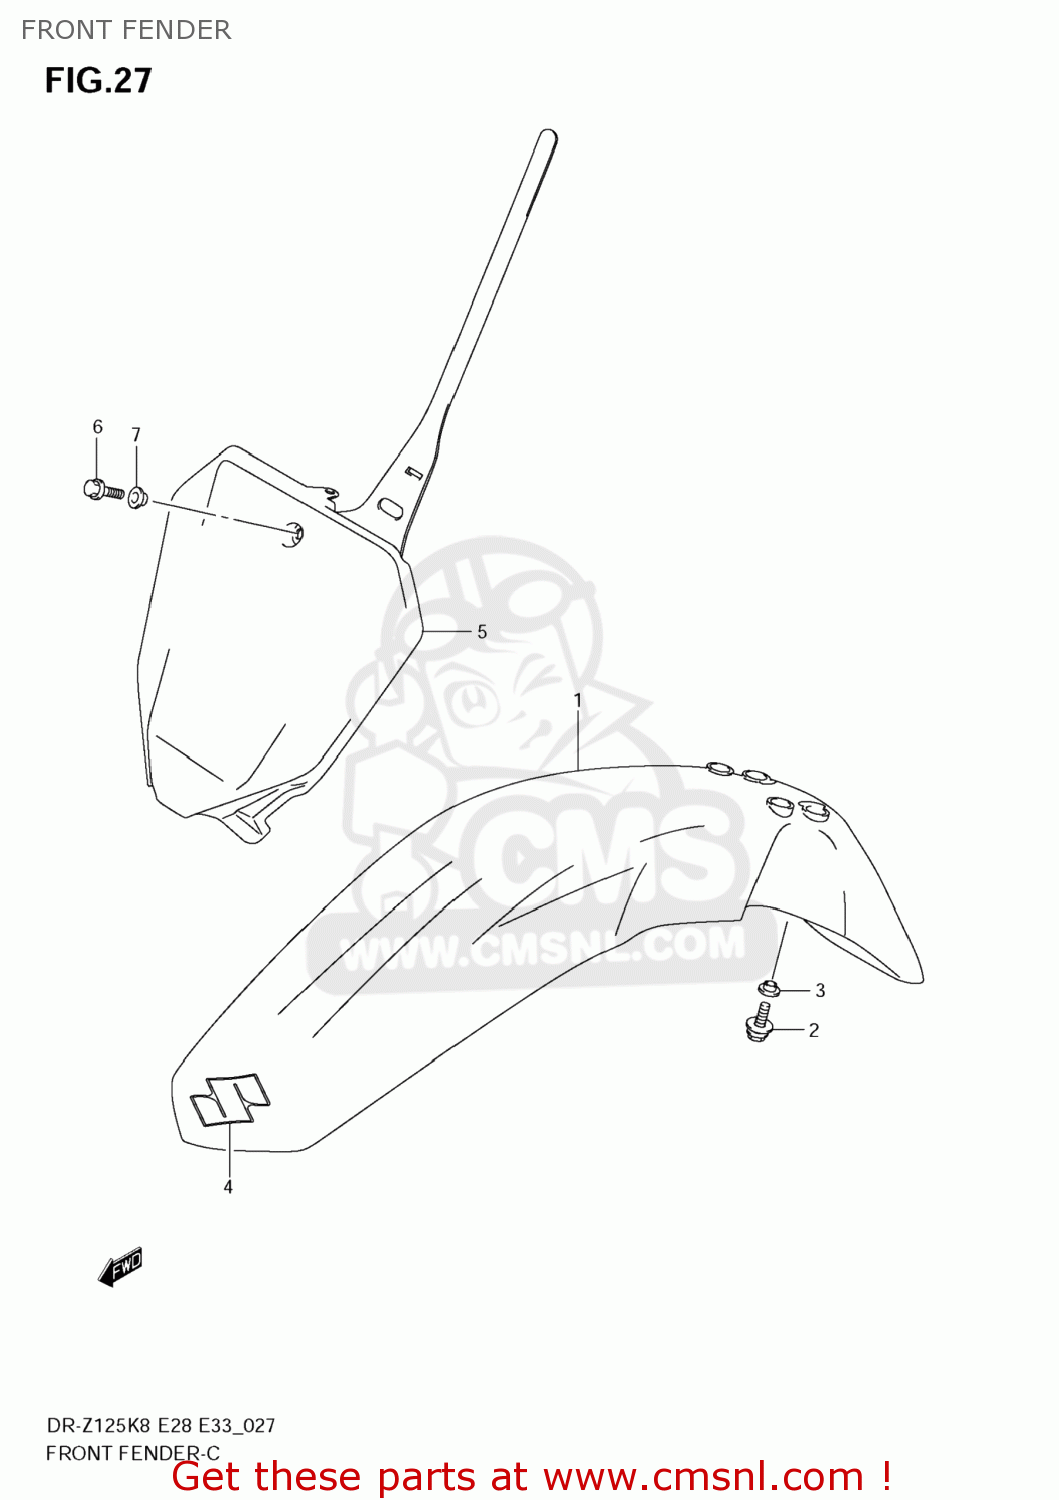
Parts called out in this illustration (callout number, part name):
1	FENDER,FR
2	BOLT(6X16)
3	WASHER
4	EMBLEM,S
5	PLATE,NUMBER FR
6	BOLT
7	WASHER
